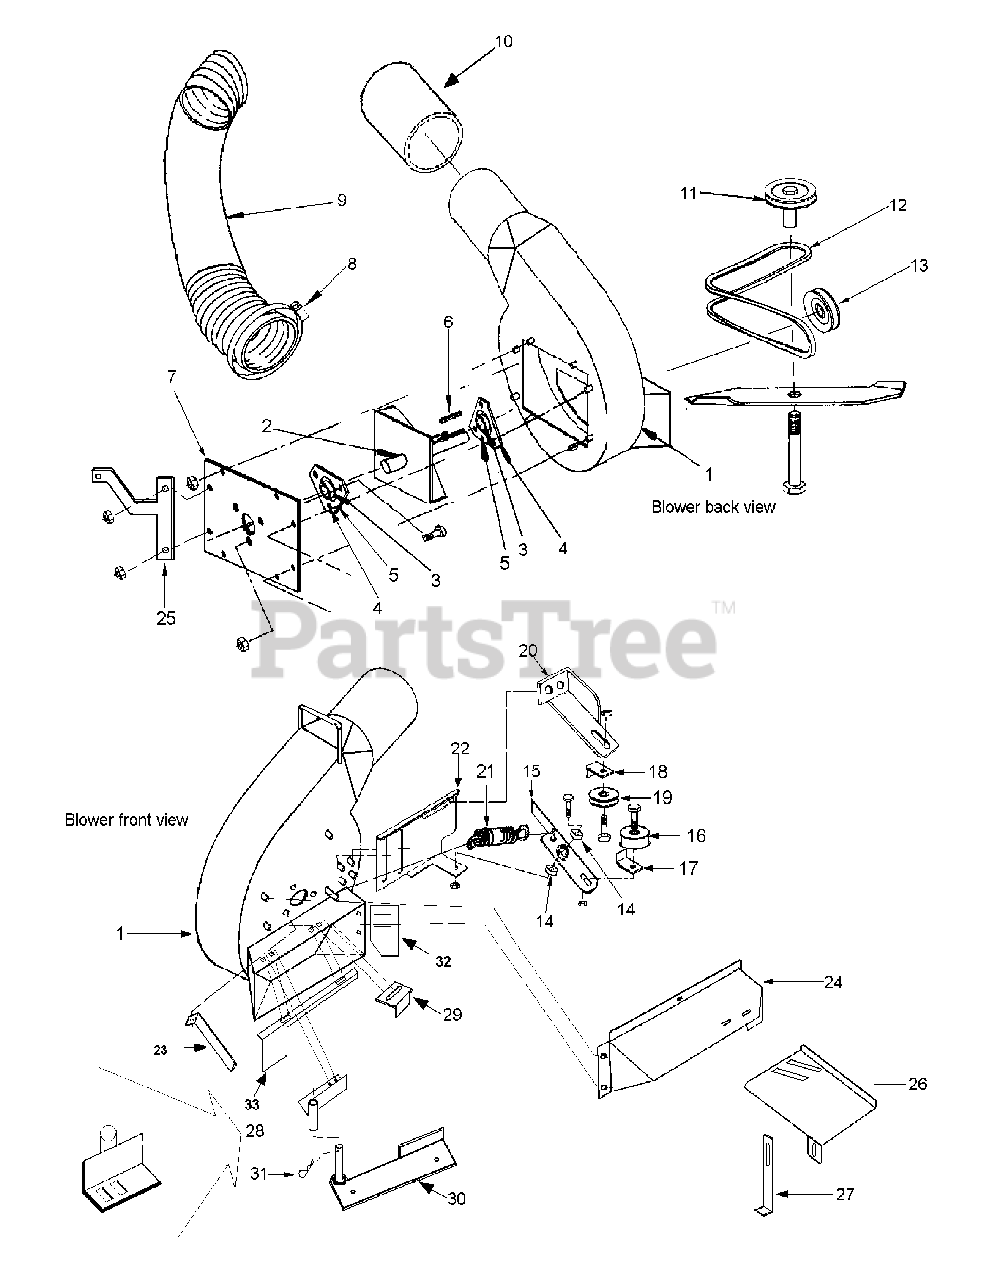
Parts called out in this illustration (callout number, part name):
1	Blower Canister
3	Fan Bearing w/ collar
4	Bearing Flangette w/ grease zerk
5	Bearing Flangette
6	Key 1/4" x 1"
7	Blower Cover Plate
8	6" Hose Clamp
9	6" x 43" Hose
10	6" Hose Insert
11	Deck Pulley
13	Blower Drive Pulley 3.5"
14	Idler Arm Bearing
15	Idler Arm
16	Flat Idler Pulley 3.25"
17	Flat Idler Pulley Bracket
18	V-Idler Pulley Bracket
19	V-Idler Pulley 3.5"
20	V Pulley Bracket
21	Idler Spring
22	Blower Pulley Bracket
23	Fan Pulley Belt Bracket
24	Blower Belt Cover
25	Pulley Bracket Support
26	Belt Guard Leg
27	Belt Guard Leg
28	Blower Mount Front
29	Blower Support Bracket
30	Blower Mount Deck
32	Blower Tab
33	Blower Blocking Plate
